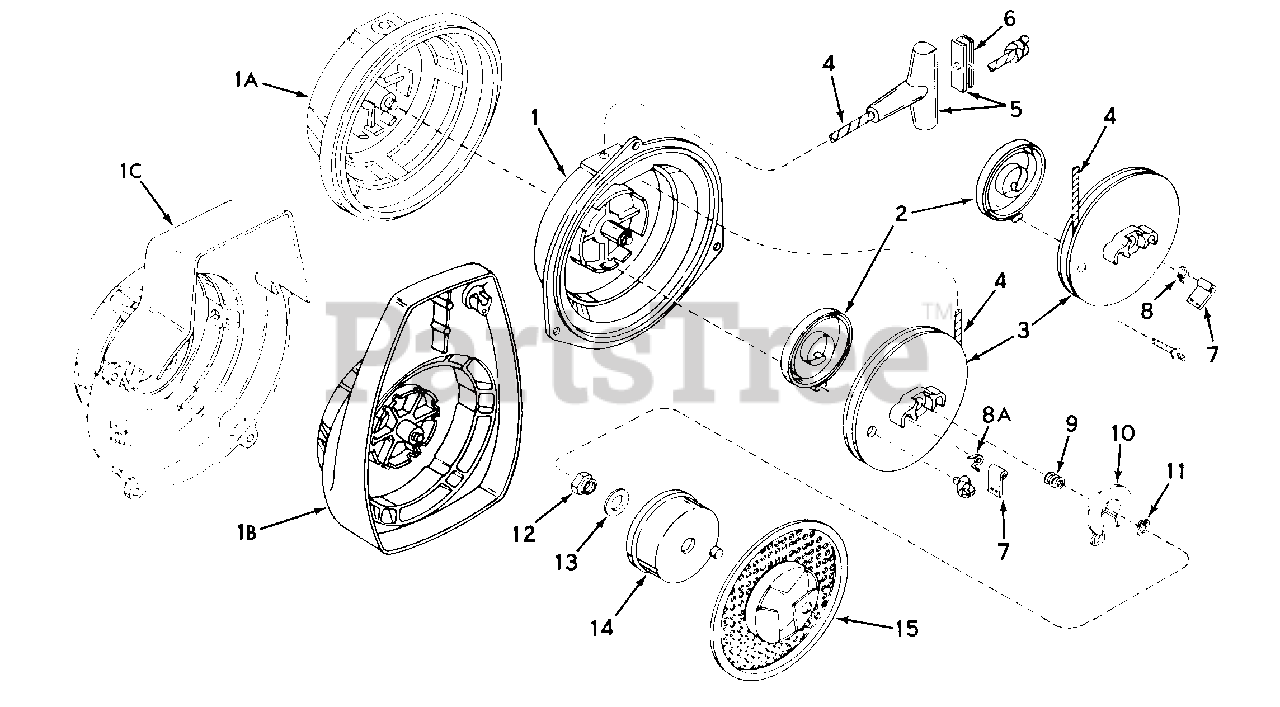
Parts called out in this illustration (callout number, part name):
1	Housing Assy., Starter
2	Spring, Rewind
3	Pulley Starter rope (Incl. 8 & 8A)
4	Rope, Starter Length 54" & 11/64" Dia .
5	Handle Assy., Starter rope (lncl. 6)
6	Insert, Handle
7	Dog, Starter
8	Return Spring, Right hand wound
9	Spring, Brake
11	"E" Ring, Truarc
12	Nut, Flywheel
14	Cup, Starter
15	Screen, Air
